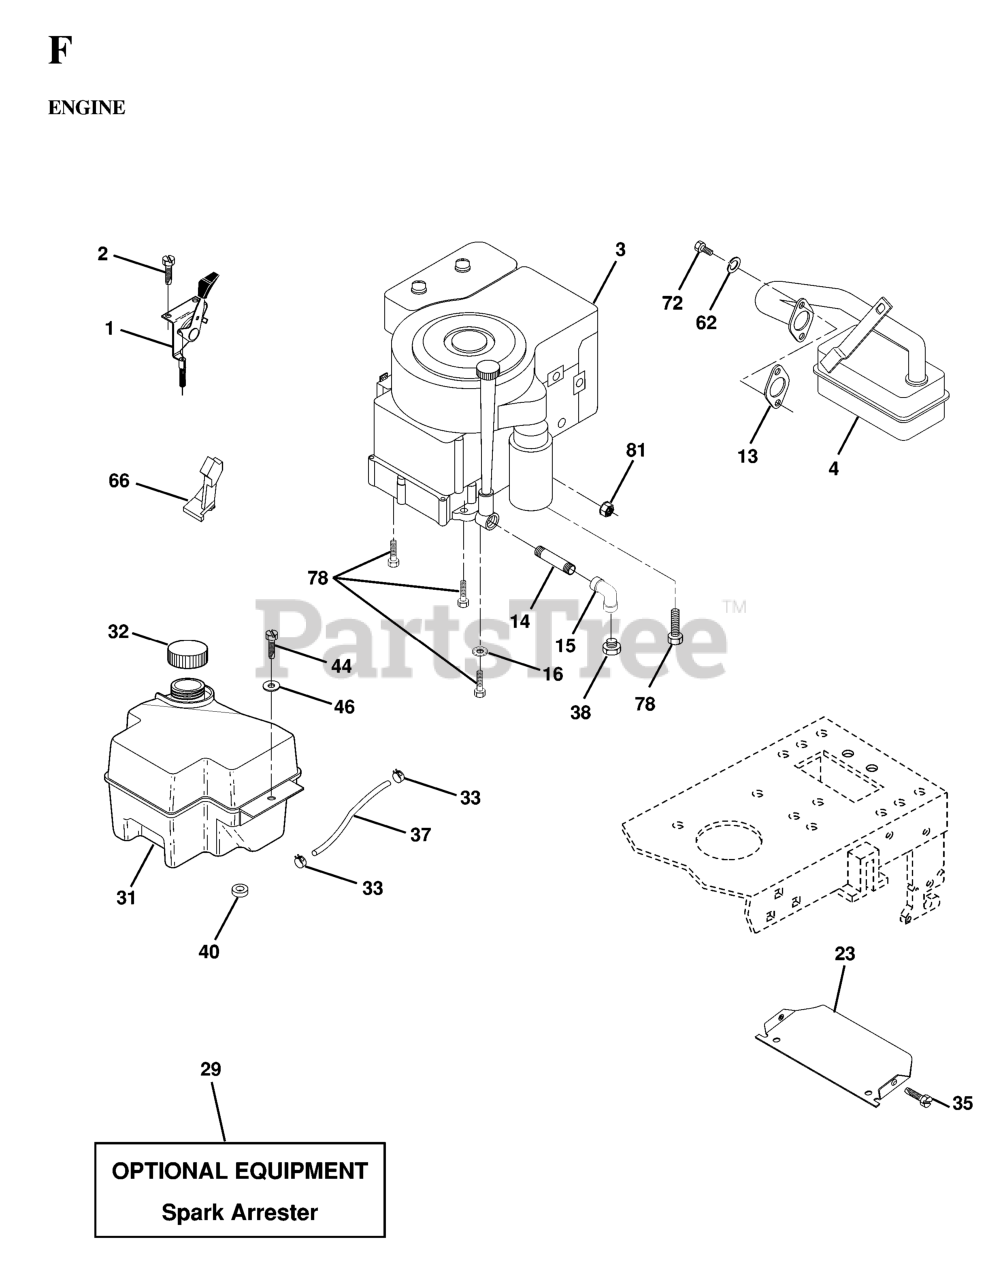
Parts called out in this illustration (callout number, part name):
1	CONTROL
2	SCREW LT
4	MUFFLER.LT.BRIGGS.14HP.IC/OHV
13	GASKET.ENG.1.313 ID.TIN PLATED
14	Nipple Pipe 3/8 Npt X 3-1/2
15	ELBOW
16	LOCKWASHER
23	SHIELD HEAT
29	KIT.SPARK ARRESTOR 794945 B&S
31	FUEL TANK
32	FUEL CAP
33	HOSE CLAMP
35	SCREW.THDROL.5/16-18X3/4.TTY
37	LINE.FUEL.20
40	BUSHING.SNAP.NYL.BLK.
44	SCREW HEX CRT
62	WASHER.LOCK.HVY.HLCL.SPR.5/16
66	STOP THROTTLE
72	SCREW
78	SCREW
81	NUT FLANGE 1/4-20 STARTER NUT
